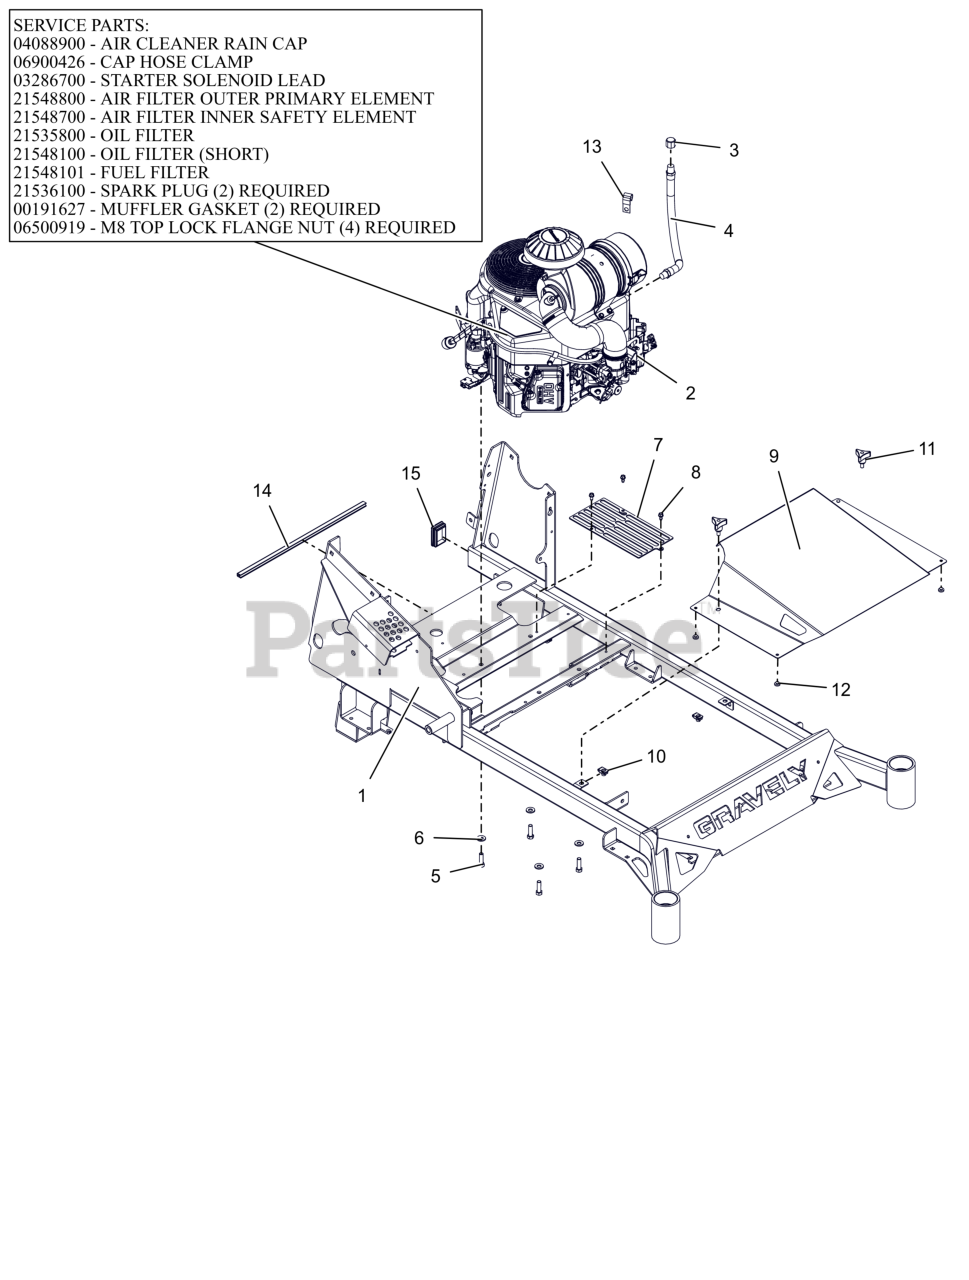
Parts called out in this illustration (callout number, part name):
1	PROSTANCE MAIN FRAME WLDMT-RED
2	ENGINE, KAWASAKI FX730
2	CAP, KAW 11065-7025
2	CLAMP, HOSE #36 SS 1.813-2.75
2	LEAD - STARTER SOLENOID
2	FILTER, OUTER
2	FILTER, INNER - KAW
2	FILTER,OIL - KAW
2	OIL FILTER, KAWASAKI FR
2	FUEL FILTER-KAWASAKI FR
2	PLUG, SPARK
2	GASKET, MUFFLER S/O
2	NUT-LK-TOP-FLG M8 ZCC
3	PIPE CAP 3/8 NPT FEMALE
4	DRAIN, M20 OIL
5	BLT, HEX .38-16X1.25 G5 ZCC NT
6	WASHER, 3/8" SPRING DISC
7	GUARD, TRANSAXLE FAN (RED)
8	SCR-TAP .25-20X.50 HWH ZCC
9	COVER, BELT
10	NUT-CLIP RETAINER 5/16-18X.56
11	KNOB,WING STUD 5/16-18 X .75
12	BUMPER GROMMET
14	STRIP, COWL
15	PLUG, RECT 1.575 x 2.362
